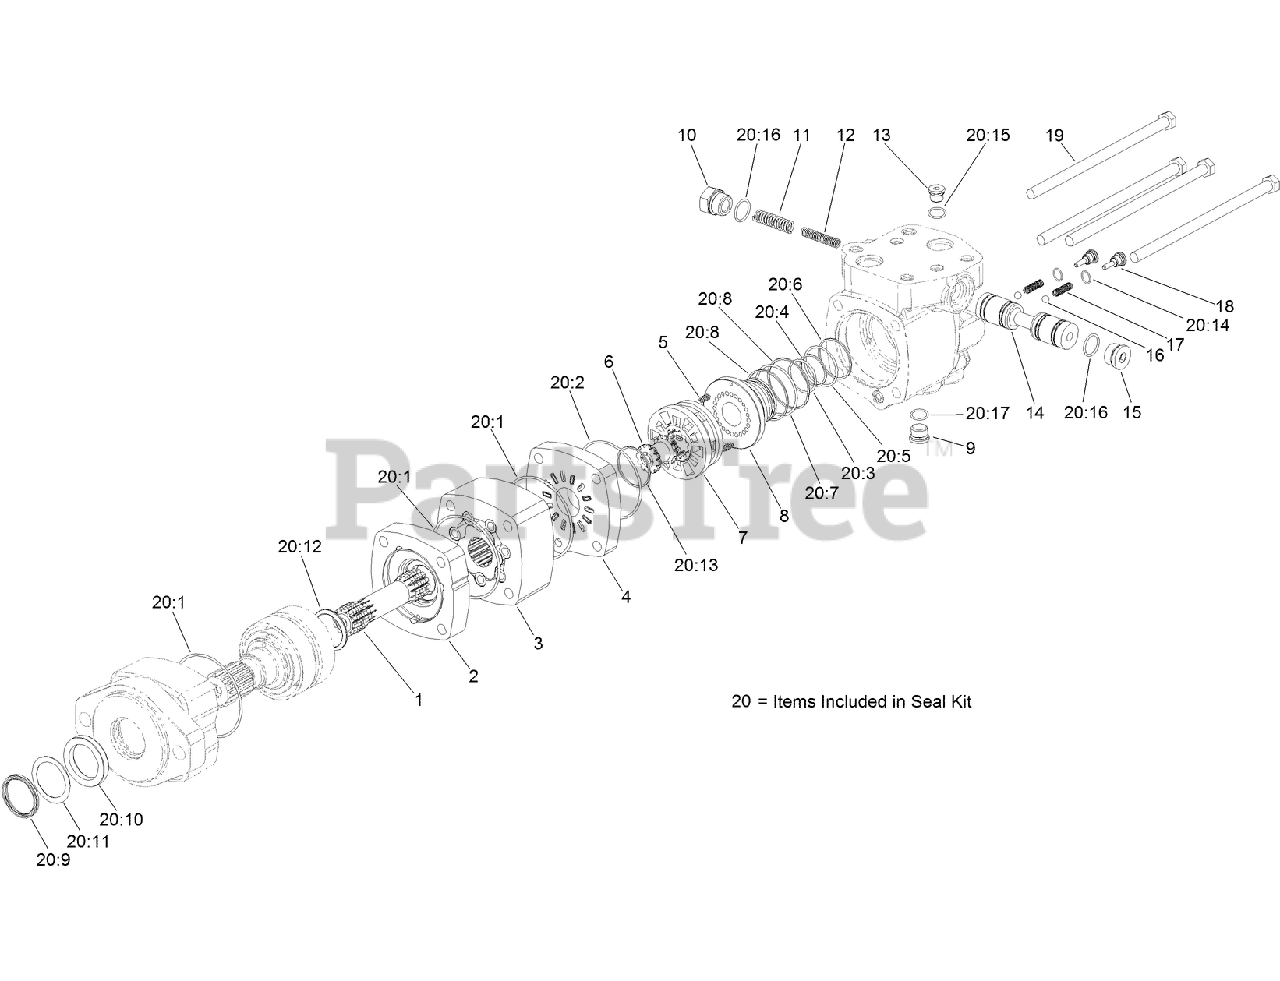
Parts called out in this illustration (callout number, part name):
1	SHAFT-DRIVE
2	PLATE-WEAR
3	GEROLER ASM
4	PLATE-VALVE
5	SPRING
6	DRIVE-VALVE
8	BALANCING RING ASM
9	PLUG ASM
10	PLUG ASM
11	SPRING-COMPRESSION
12	SPRING-COMPRESSION
13	PLUG ASM
14	SPOOL-CONTROL
15	PLUG ASM
16	BALL-STEEL
17	SPRING-COMPRESSION
18	PLUG ASM
19	SCREW-CAP
20	SEAL KIT
20:1	O-RING
20:2	O-RING
20:3	O-RING
20:4	RING-BACKUP
20:5	O-RING
20:6	RING-BACKUP
20:7	O-RING
20:8	RING-BACKUP
20:9	SEAL
20:10	SEAL
20:11	Washer-Backup
20:12	Seal-Shaft Face
20:13	SEAL
20:14	O-RING
20:15	O-RING
20:16	O-RING
20:17	O-RING
